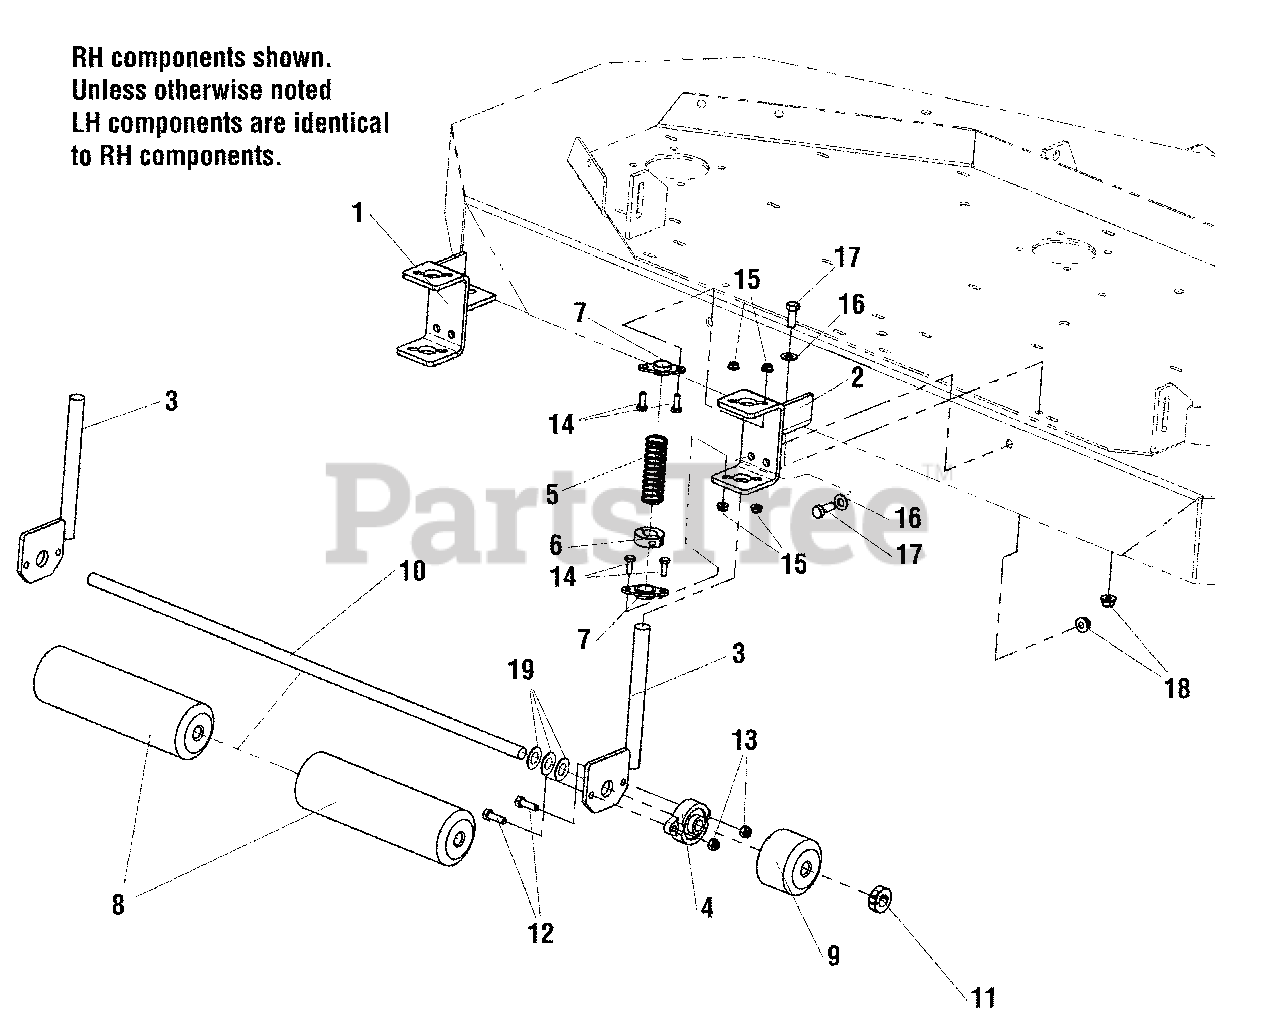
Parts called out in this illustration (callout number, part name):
1	WELD, ROLLER MT, COBALT - RH - ORANGE
2	WELD, ROLLER MT, COBALT - LH - ORANGE
3	WELD, ROLLER SLIDE
4	BEARING, FLANGE, 5/8
5	SPRING, COMPRESSION
6	COLLAR, 3/4" DOUBLE SPLIT
7	BUSHING, FLANGE
8	ROLLER, DECK
9	ROLLER, PLASTIC, .64 X 3.00 X 2.25
10	SHAFT, 5/8 X 28.88
11	COLLAR, 5/8" SPLIT
12	BOLT, 5/16-18 X 1" GD5
13	NUT 5/16-18 HEX NYLON LOCK
14	BOLT, 1/4-20 X .75 NA
15	NUT, 1/4-20 HEX NYLOCK FLANGE (5025391)
16	WASHER, 3/8 SAE
17	BOLT, 3/8-16 X 1-1/4" GD5
18	NUT, 3/8-16 HEX NYLOCK FLANGE
19	WASHER, 5/8" SAE
